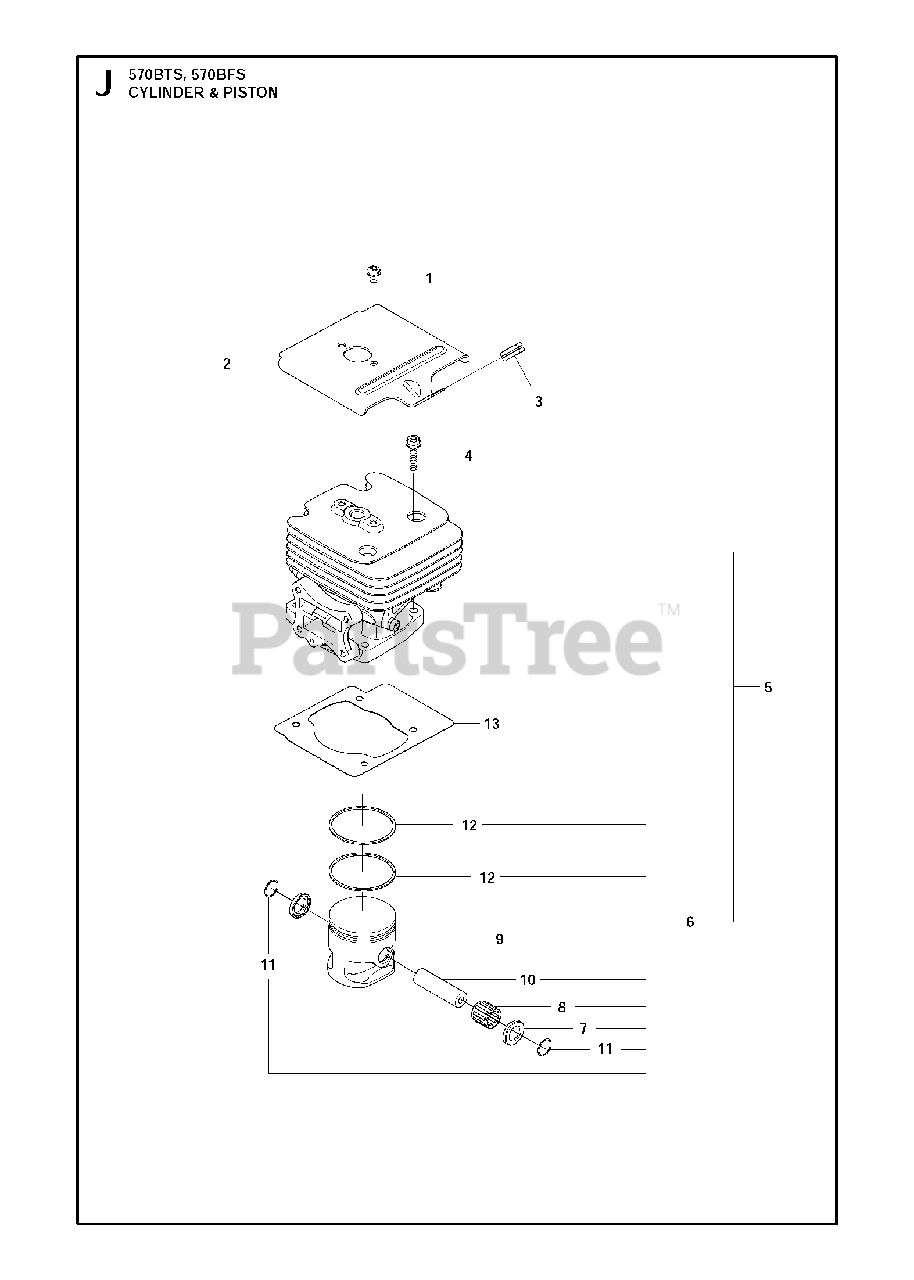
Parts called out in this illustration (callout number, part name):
5	CYLINDER ASSY
6	PISTON ASSY
7	WASHER
8	BEARING
9	PISTON
10	PIN
11	SNAP RING
12	RING
